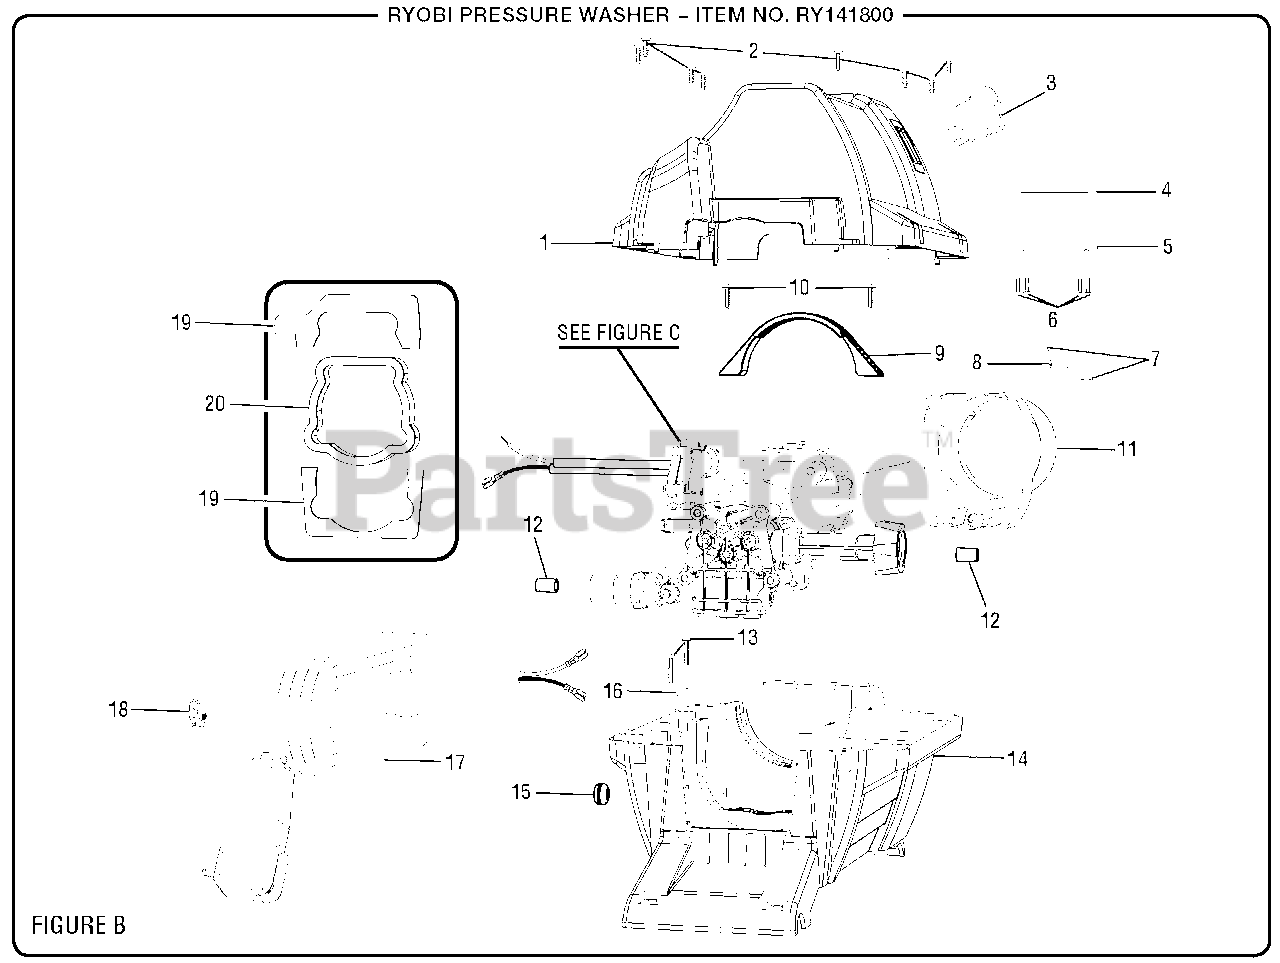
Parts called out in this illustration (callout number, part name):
1	Top Motor Housing
2	Screw (M4 x 15 mm. Pan Hd.)
4	Switch Cover Gasket
5	Switch Cover
6	Screw (M2.9 x 14 mm, Pan Hd.)
9	Motor Bracket
10	Screw w/Washer (M4 x 12 mm, Pan Hd.)
11	Air Shroud
13	Screw (M3.5 x 20 mm, Pan Hd.)
14	Lower Motor Housing
16	Cord Clamp
17	Power Cord
18	Electric Cord Clip
19	Upper and Lower Gasket Assembly
